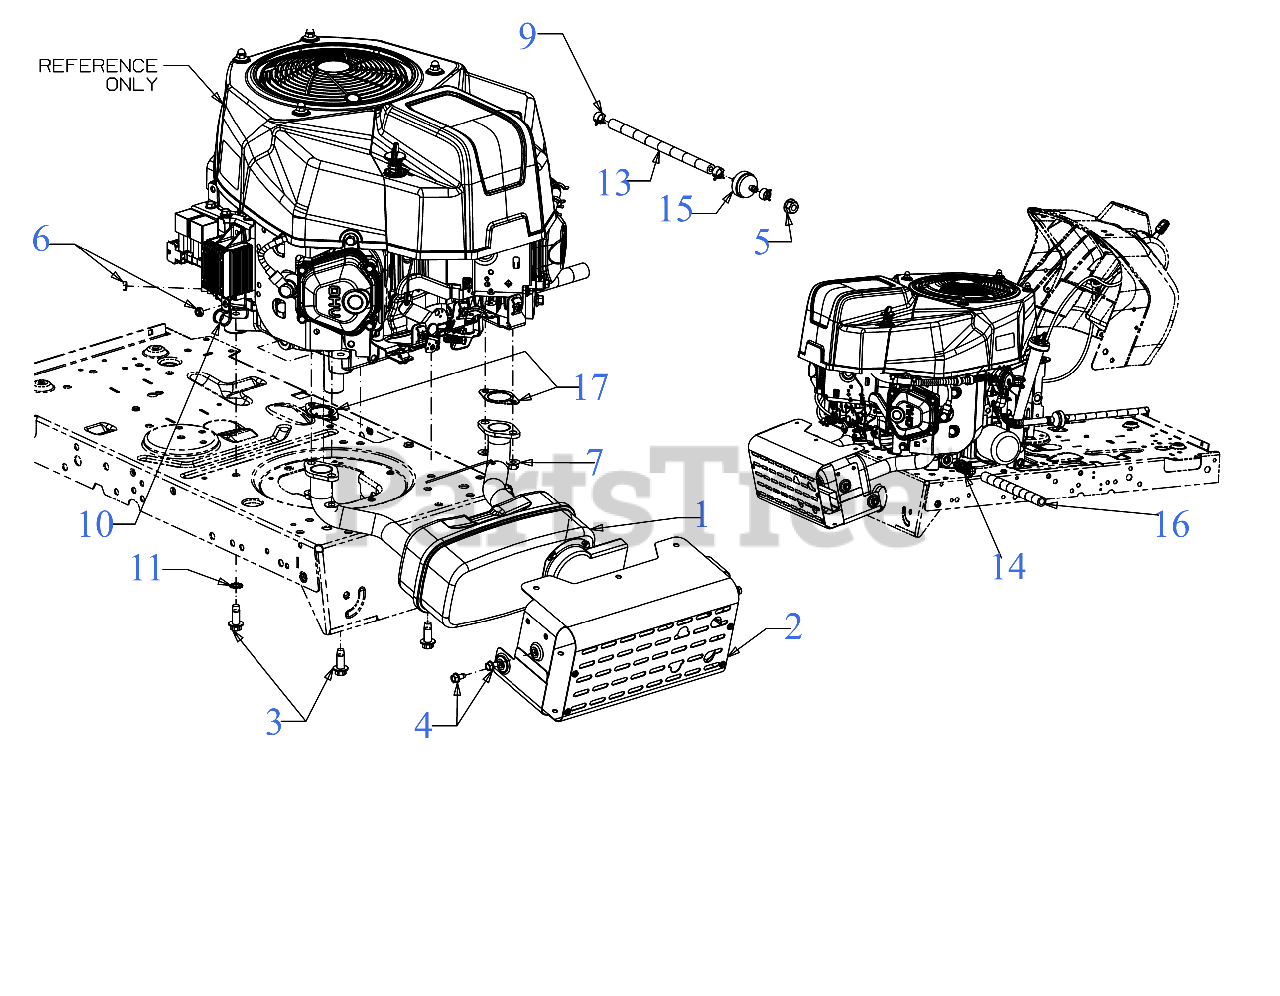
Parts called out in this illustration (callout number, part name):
1	MUFFLER (W/DEFLECTOR)
3	SCREW 3/8-16 x 1
4	SCREW 1/4-20 X.500
5	FLANGE LOCK NUT
6	HEX NUT IK:M6
7	HEX FLANGE NUT M8X
9	HOSE CLAMP 1/20
10	CLAMP
11	LOCK WASHER 3/8
13	FUEL HOSE LOW PERMEATION 13"
14	OIL DRAIN VALVE
15	FUEL FILTER
15	Genuine Factory Parts FUEL FILTER
16	DRAIN HOSE 14''
17	EXHAUST GASKET
